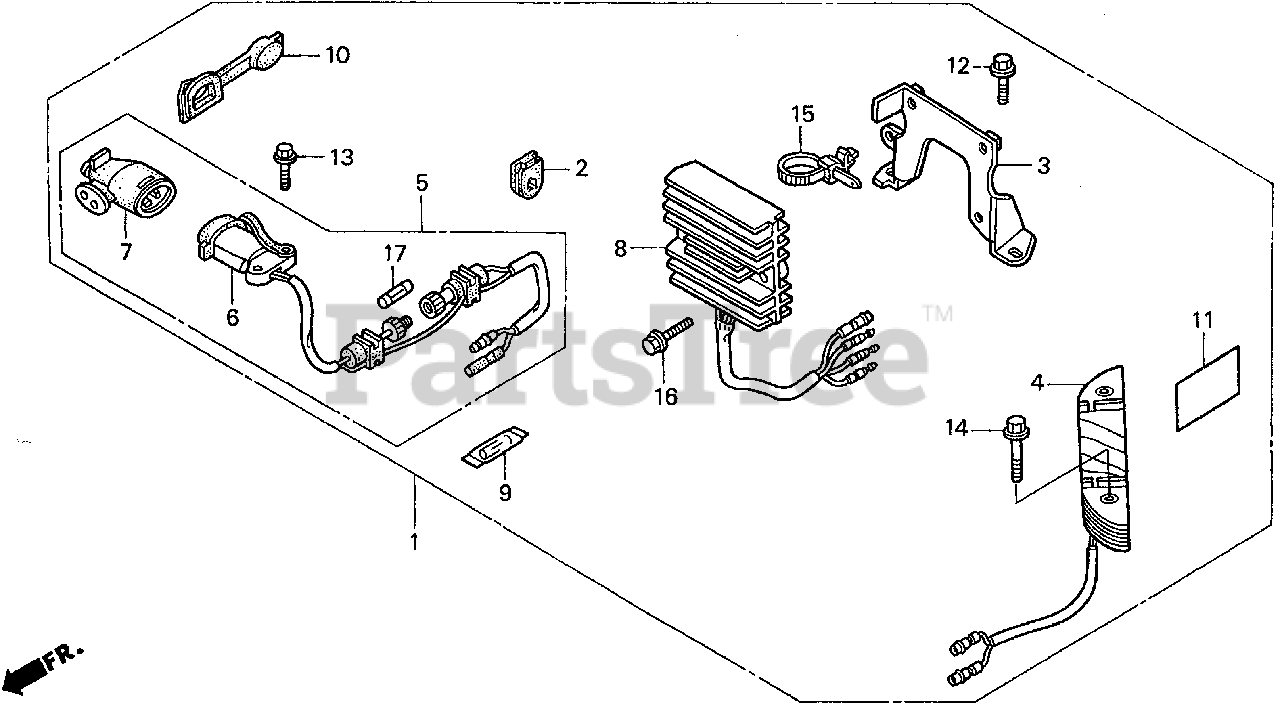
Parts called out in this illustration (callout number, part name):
1	RECEPTACLE KIT, CHARGE (6A)
2	GROMMET, WIRE
3	BRACKET, REGULATOR
4	COIL ASSY., CHARGE (12V-6A)
5	RECEPTACLE ASSY., CHARGE
6	RECEPTACLE
7	PLUG, RECEPTACLE
8	REGULATOR ASSY. (RECTIFIER)
9	FUSE, SPARE (15A)
10	GROMMET, CASE (LOWER) (C)
11	MARK, RECEPTACLE (6A)
12	BOLT, FLANGE (6X12)
13	BOLT, FLANGE (5X22)
14	BOLT, FLANGE (6X35)
15	STRAP, CABLE (118MM) *NH1L*
16	BOLT, FLANGE (6X20)
17	FUSE A (15A)
